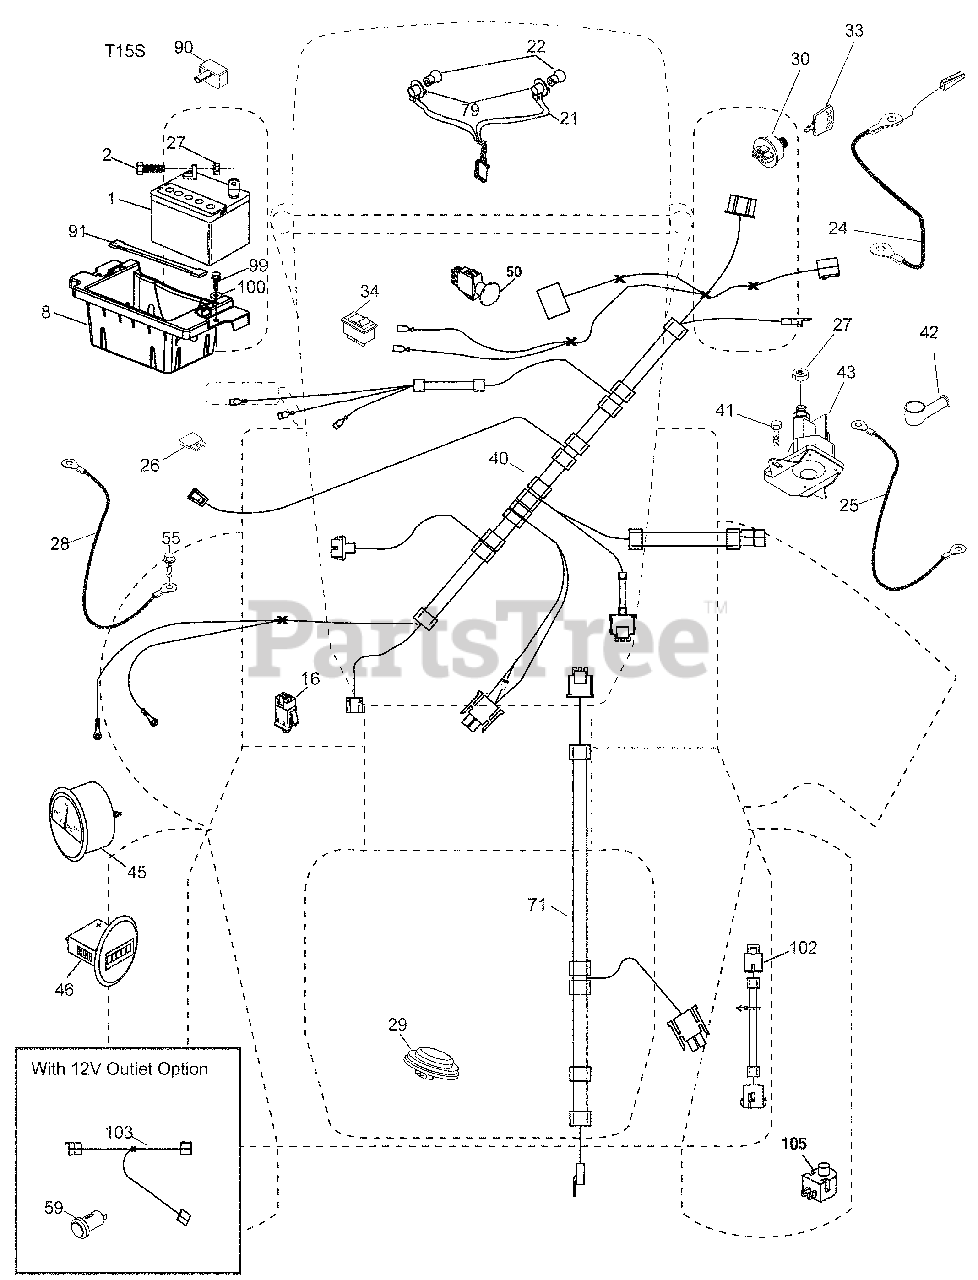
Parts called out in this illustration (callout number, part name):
1	Battery
2	Bolt Hex Head 1/4-20 x 3/4
8	Box Battery
16	Switch Interlock Push-In
21	Harness Socket Light w/4152J
22	Bulb Light
24	Cable Battery
25	Cable Starter
27	Nut Keps Hex 1/4-20 unc
28	Cable, Ground
29	Switch, Seat
30	Switch, Ign
34	Switch Light / Reset
40	Harness Ign. Dash
41	Screw Thd Cut 1/4-20 x 1/2
42	Cover, Terminal
43	Solenoid
45	Ammeter Gauge Round Snap-in
46	Gauge Round snap-in Hrmtr
50	Switch PTO
55	Screw Thdrol 5/16-18 x 3/4 TYTT
59	Outlet 12-Volt
71	Harness Ign.
79	Socket Asm Bulb Twistlock
90	Cover Terminal
91	Strap Battery
99	Screw Hexwsh Thdrol 1/4-20 x 3/4
100	Washer 9/32 x 7/8 x 16 Ga.
101	Harness Pigtail
102	Harness Pigtail
103	Harness 12-Volt Pigtail
105	Switch Reverse TT Pedal Control
